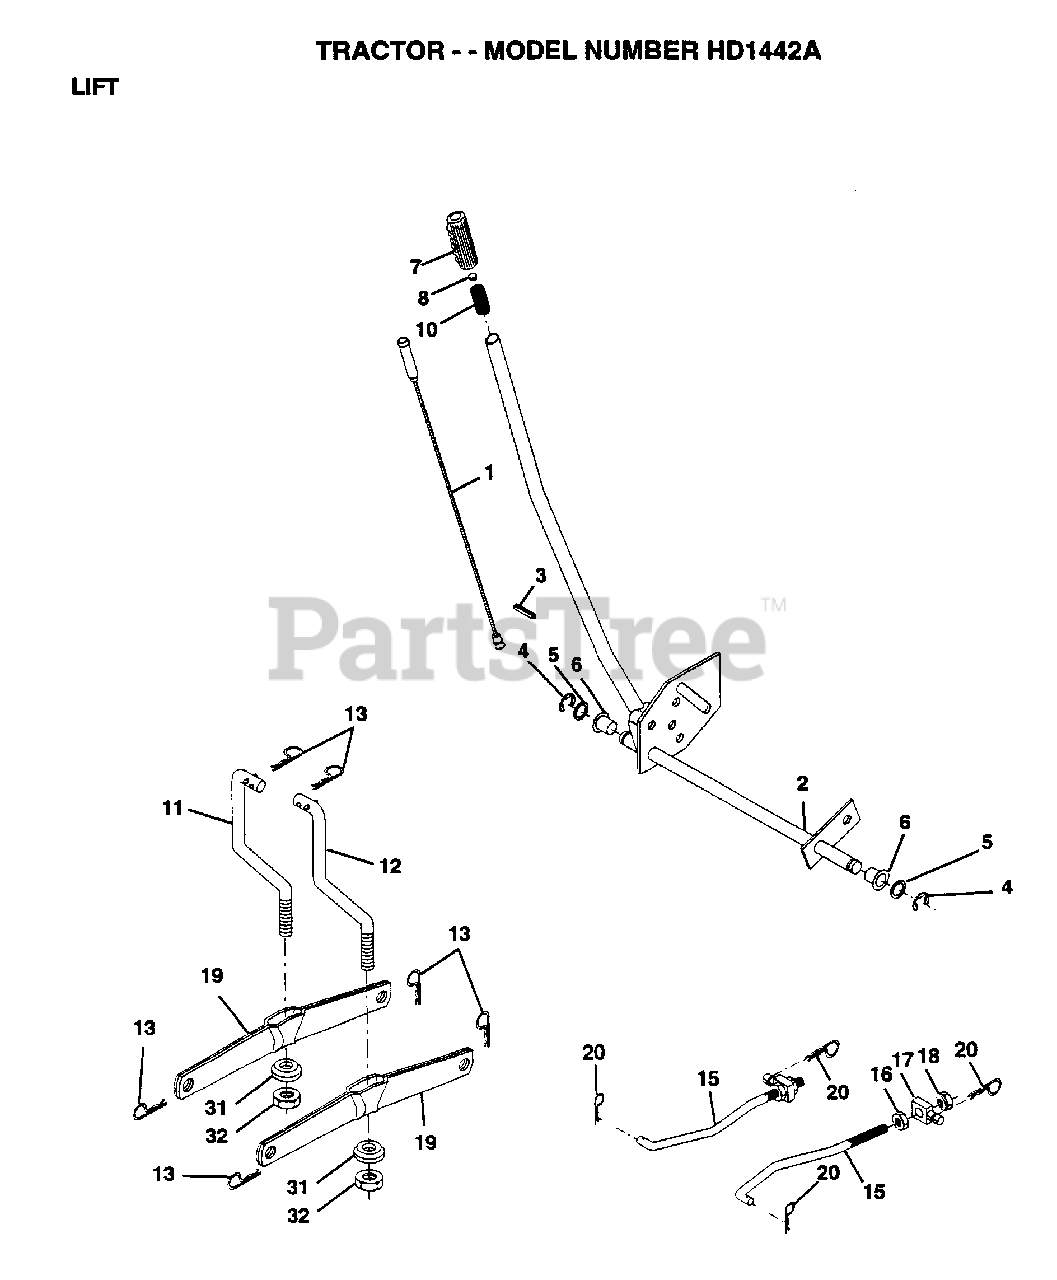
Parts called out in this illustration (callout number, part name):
1	WIRE ASM
2	HANDLE.LIFT.LH.
3	PIN GROOVE
5	WASHER
6	NYLON BEARING
7	GRIP HANDLE
15	LINK.FRONT
16	NUT
17	TRUNION
18	NUT.LK.W/WSH.1/2.
19	ARM SUSP REAR
20	RETAINER.SPRING
31	BEARING PVT LH
32	NUT.CROWNLOCK.3/8
